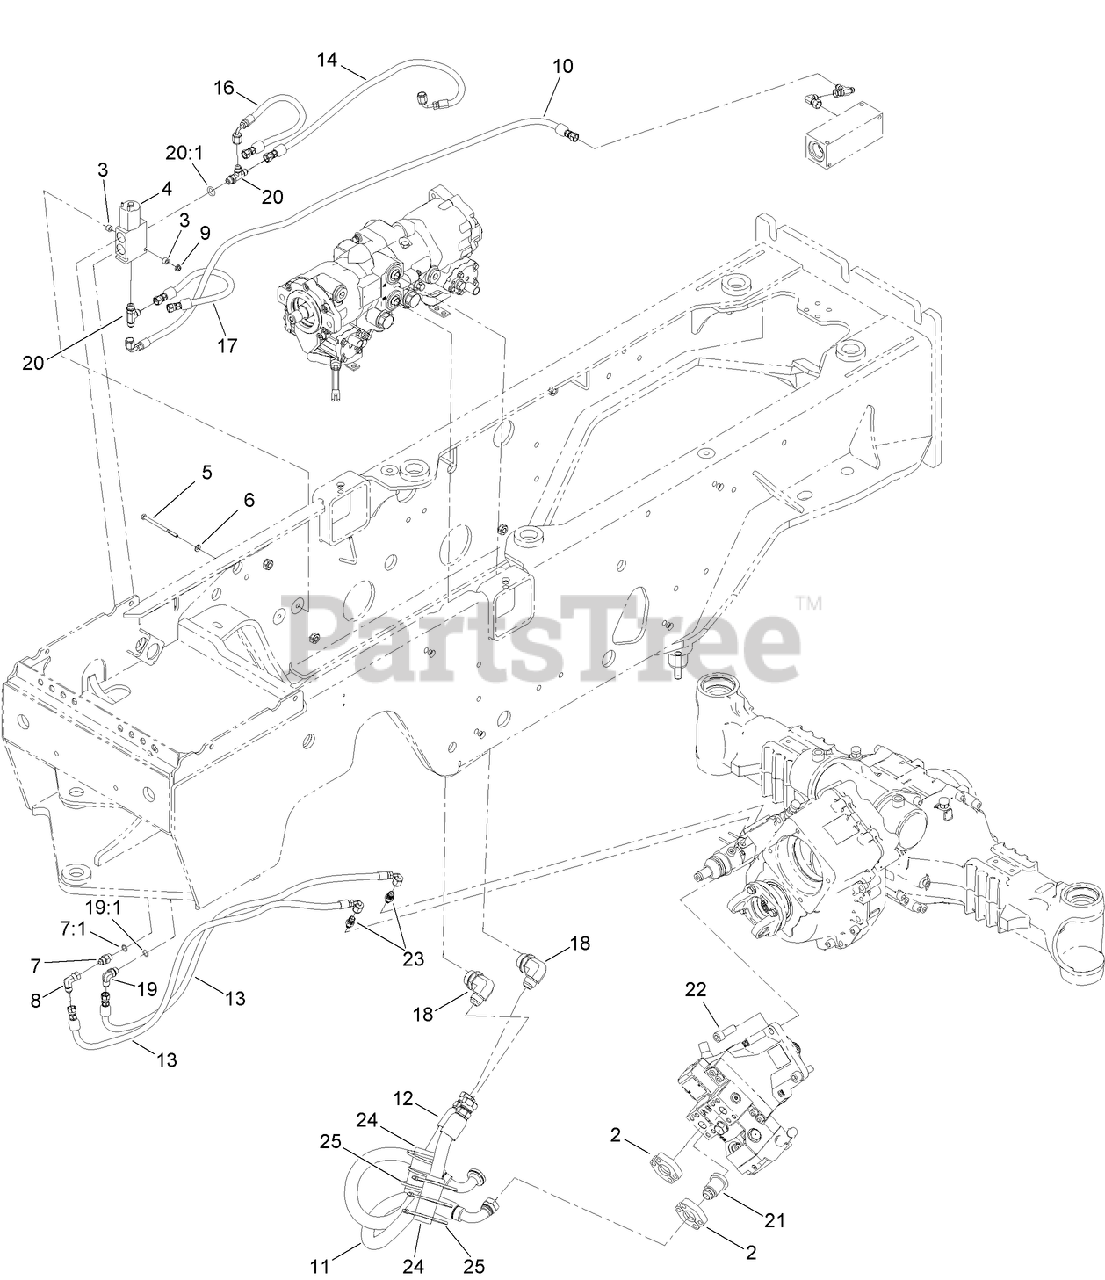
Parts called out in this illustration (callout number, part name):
2	3/4 INCH SPLIT FLANGE KIT
3	SPACER
4	SOLENOID VALVE ASM
5	SCREW-HH
6	WASHER-FLAT
7	FITTING-STRAIGHT
7:1	O-RING
8	ELBOW-SWIVEL, 90 DEG
9	NUT-HF
10	HOSE ASM
11	HOSE ASM
12	HOSE ASM
13	HOSE ASM
14	HOSE ASM
16	HOSE ASM
17	HOSE ASM
19	FITTING-ELBOW, 90 DEG
19:1	O-RING
20	FITTING-TEE
20:1	O-RING
21	FITTING-STRAIGHT
22	SCREW-HSH
23	ADAPTER
24	PROTECTOR-HOSE
25	TIE-CABLE
